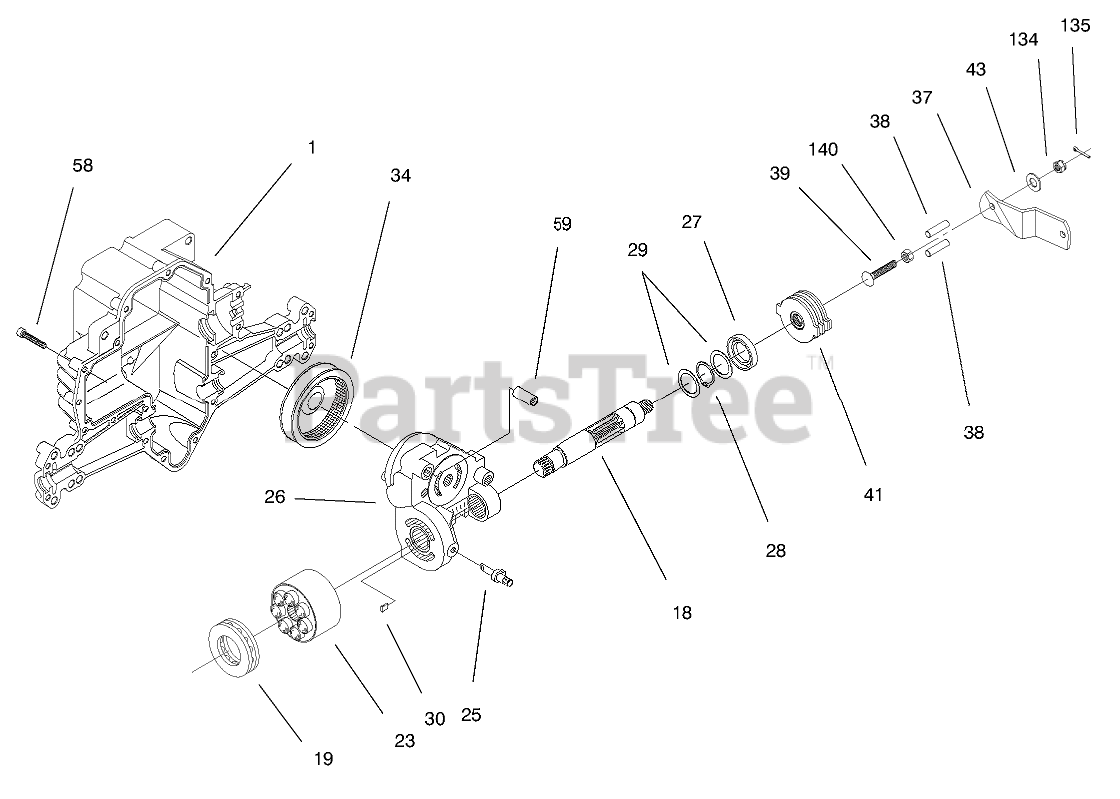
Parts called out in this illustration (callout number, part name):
1	HOUSING - LOWER
18	SHAFT - MOTOR
19	BEARING-THRUST
23	CYLINDER BLOCK ASM
25	ACTUATOR-BYPASS
26	Centersection ASM
27	SEAL - LIP
28	RING - RETAINING
29	WASHER
30	PLATE-BYPASS
34	ELEMENT - OIL FILTER
37	LEVER - BRAKE
38	PIN - ACTUATING
39	BOLT 5/16-18 X 1-3/4
41	KIT-BRAKE ROTOR/STATOR
43	WASHER-PIVOT
134	NUT-CASTLE
135	PIN-COTTER
140	NUT-LOCK, NI
